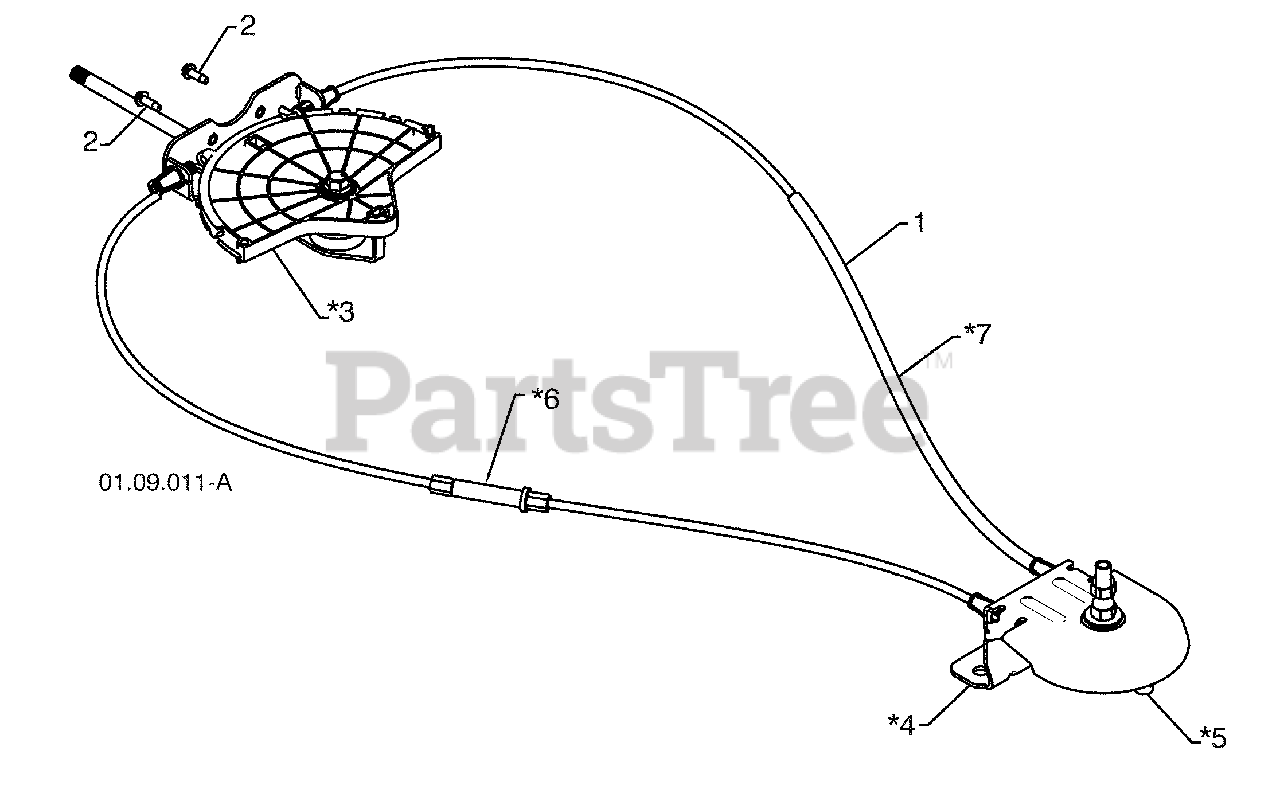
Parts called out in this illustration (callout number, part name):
1	LEVER/CABLE ROTATOR ASSEMBLY
2	SCREW 10-24 X .625
3	ROTATOR HEAD
4	ROTATOR PIVOT BRACKET
5	PULLEY PIVOT
6	CABLE ASSEMBLY ADJUSTABLE
7	CABLE ASSEMBLY HEAT SHIELD
